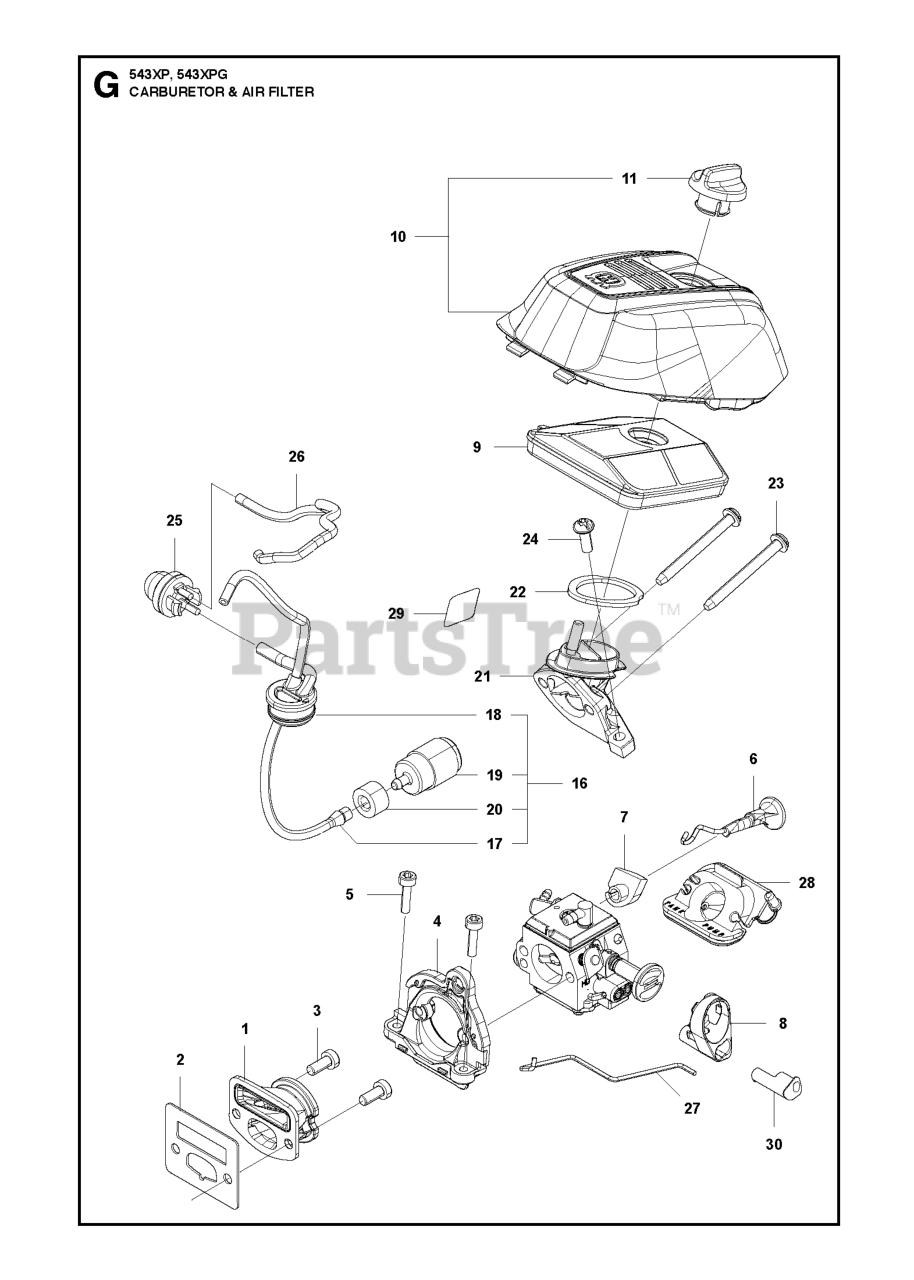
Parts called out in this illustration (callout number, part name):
1	INLET PIPE ASSY
3	BOLT
4	FLANGE ASSY
5	BOLT
6	ROD CHOKE XC25
8	GROMMET ID
10	AIR FILTER COVER
11	KNOB XC25
16	FUEL HOSE
17	FUEL HOSE L215
18	GROMMET
20	COLLAR
22	SEAL MANIFOLD
24	SCREW M5 X 14
25	PRIMARY BTN
26	FUEL HOSE L170
27	THROTTLE ROD
